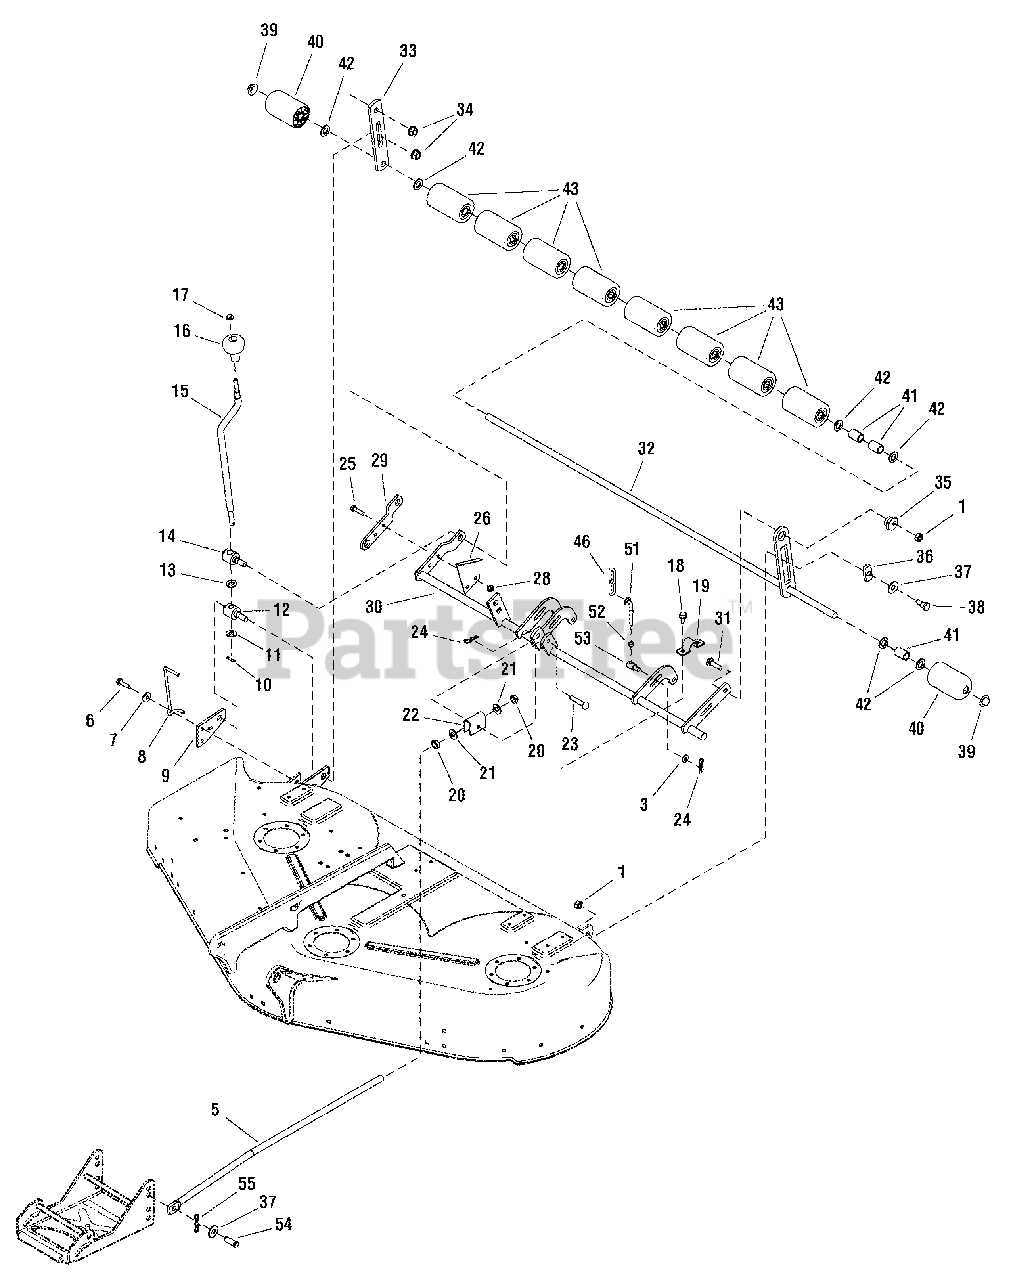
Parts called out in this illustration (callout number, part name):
1	NUT, Hex Toplock Spiralock Flange 3/8-16
3	WASHER, 3/8
5	ROD, Adjusting
6	SCREW, Hex Washer Head Taptite 5/16-18 x 1-1/4
7	WASHER, 5/16
8	INDICATOR, Cutting Height
9	PLATE, Mower Support
10	PIN, Spring
11	WASHER, Detent
12	TRUNNION, 1-1/4
13	WASHER, 1/2
14	TRUNNION, 1-1/4
15	CRANK, Height Adjusting
16	KNOB, Spinner
17	NUT, Push Pal 3/8 Diameter Stud Capped
18	SCREW, Hex Washer Head Taptite 5/16-18 x 3/4
19	STRAP
20	NUT, Hex 5/8-11
21	WASHER, 5/8
22	TRUNNION
23	PIN, Round Head Drilled 3/8 x 2
24	CLIP, Hair Pin
25	CAPSCREW, Hex Head 5/16-18 x 1-1/4 G5
26	BRACKET, Height of Cut 16GA
28	NUT, Hex Flange 5/16-18, Whiz Lock Small
29	ARM, Rear R.H.
30	SHAFT ASSEMBLY, Rocker 50"
31	BOLT, Carriage, 3/8-16 x 1-1/2, G5
32	SHAFT & BAR ASSEMBLY, Roller 50"
33	BAR, Roller
34	NUT, Hex Flange 1/2-13 Two-Way Lock
35	NUT, Hex Adjusting, .99 DIA .687
37	WASHER, 1/2
38	BOLT, Shoulder, 3/8-16 X 1.34
39	NUT, Push for 5/8 Diameter Stud Capped
40	ROLLER, Rounded
42	WASHER, 5/8
46	CHAIN, Link
51	ROD, Height Adjusting, Chain, 2.55" Long
52	NUT, Hex Jam 5/16-18
54	PIN, Yoke
55	PIN, Cotter Locking
